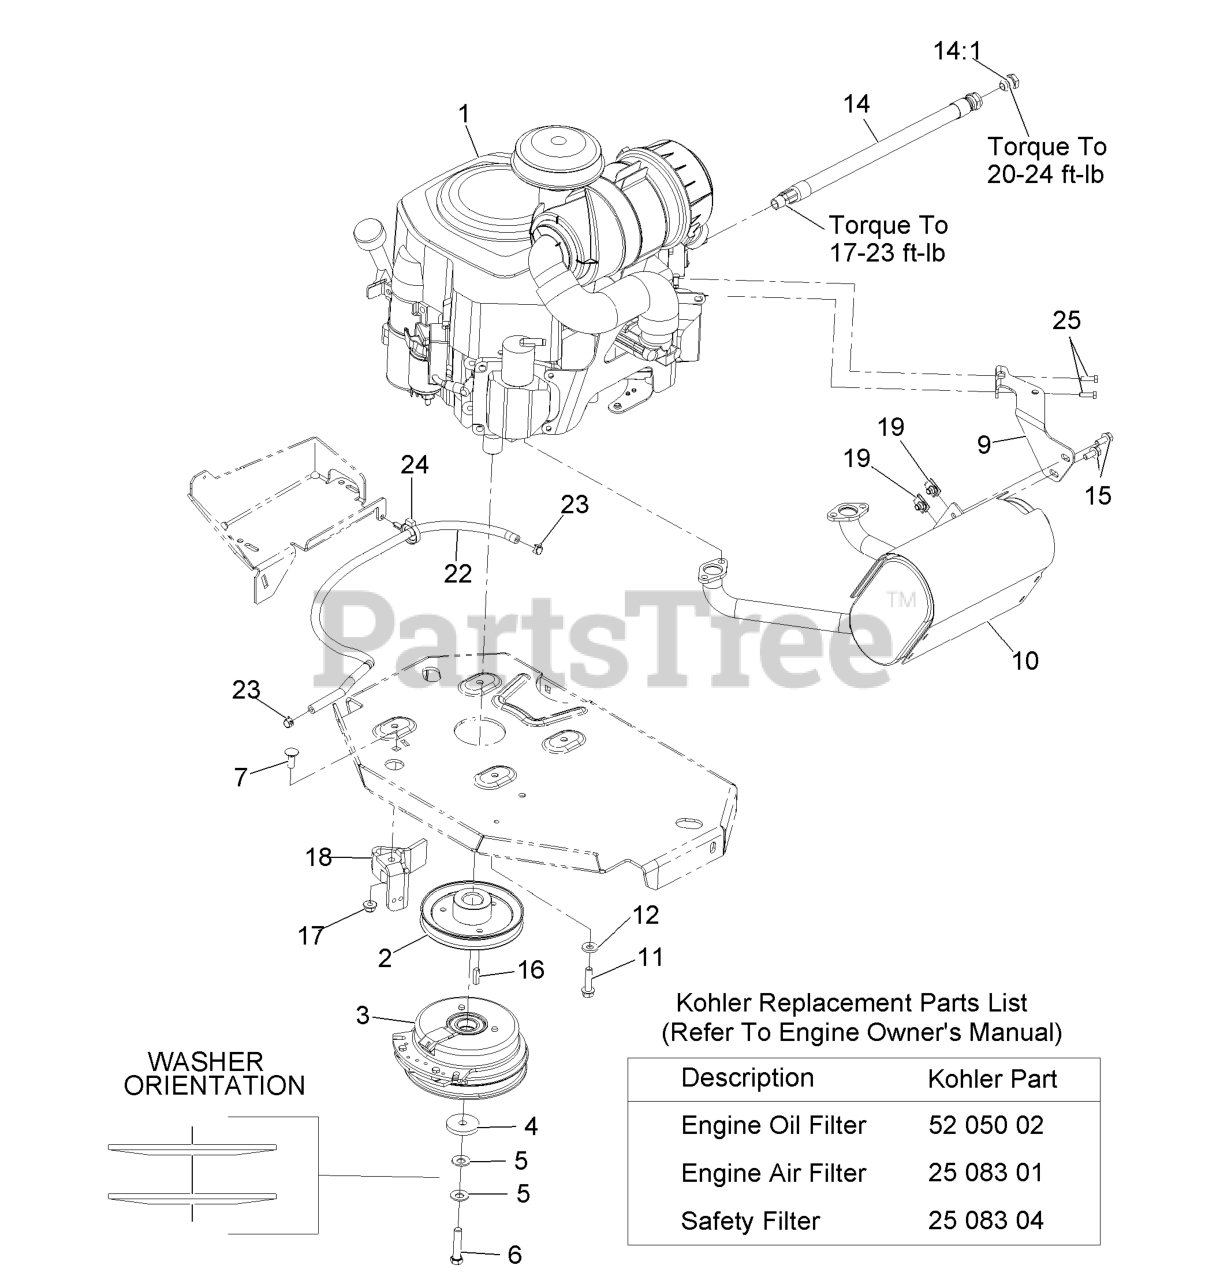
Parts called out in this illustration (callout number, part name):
1	Engine,Koh 27hp Hd
2	SHEAVE
3	CLUTCH KIT
4	WASHER-CLUTCH
5	WASHER-SPRING
6	SCREW-HH W/LOCTITE
7	SCREW-CARR
9	MUFFLER BRACKET KIT
11	SCREW-HWH
12	WASHER-BELLEVILLE
15	SCREW-HHF
17	NUT-HF, NI
18	CLUTCH-ANCHOR
22	HOSE-FUEL
23	CLAMP-HOSE
24	CLAMP-HOSE
25	SCREW-HH M6-1 X 20Mm W/Patch
